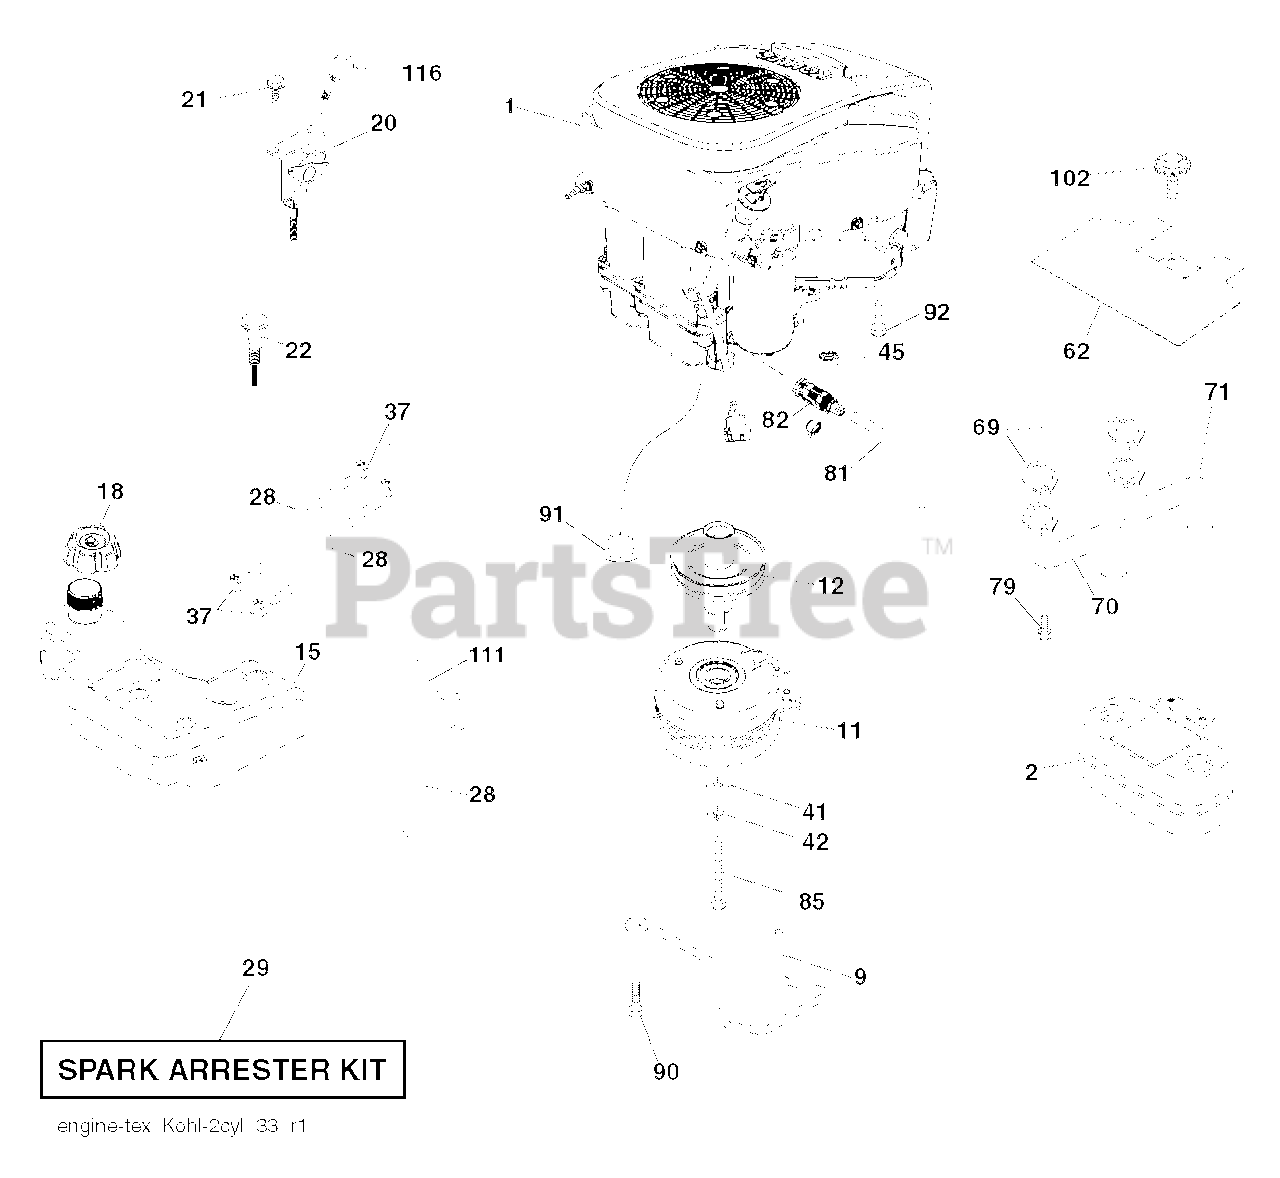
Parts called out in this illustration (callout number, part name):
2	MUFFLER.ASM.TWN.EXTNDED.DFLCTR
9	KEEPER.BELT.ENGINE.4.2
11	CLUTCH. 5.0 PD. 2.5 OFFSET
12	PULLEY.EXTENDED.SHAFT.GROUND
15	TANK.ASM.FUEL.3GA.CARB
18	CAP ASSY FUEL 3" GRAY
20	CONTROL.THROTTLE.PRO.KOHLER
21	SCREW.#10 X 0.750.BOS
22	CONTROL, CHOKE
28	LINE.FUEL.64"REAR.EMIS
29	KIT.SPARK ARRESTOR 794945 B&S
37	HOSE CLAMP
42	LOCKWASHER
45	NUT
62	SHIELD.HEAT.MUFFLER
70	TUBE.EXHAUST.LH.FR961/FR730
71	TUBE.EXHAUST.RH.FR961/FR730
79	SCREW.SOCKET HD.5/16-1
81	TUBE, DRAIN OIL ASM.
82	VALUE.OIL.DRAIN
85	BOLT.HEX.7/16-20 X 5
90	SCREW 3/8-16X1
91	BUSHING.1.375OD
92	SCREW 3/8-16X1
102	SCREW
111	RP PURGE LINE
116	KNOB - SHIFT
